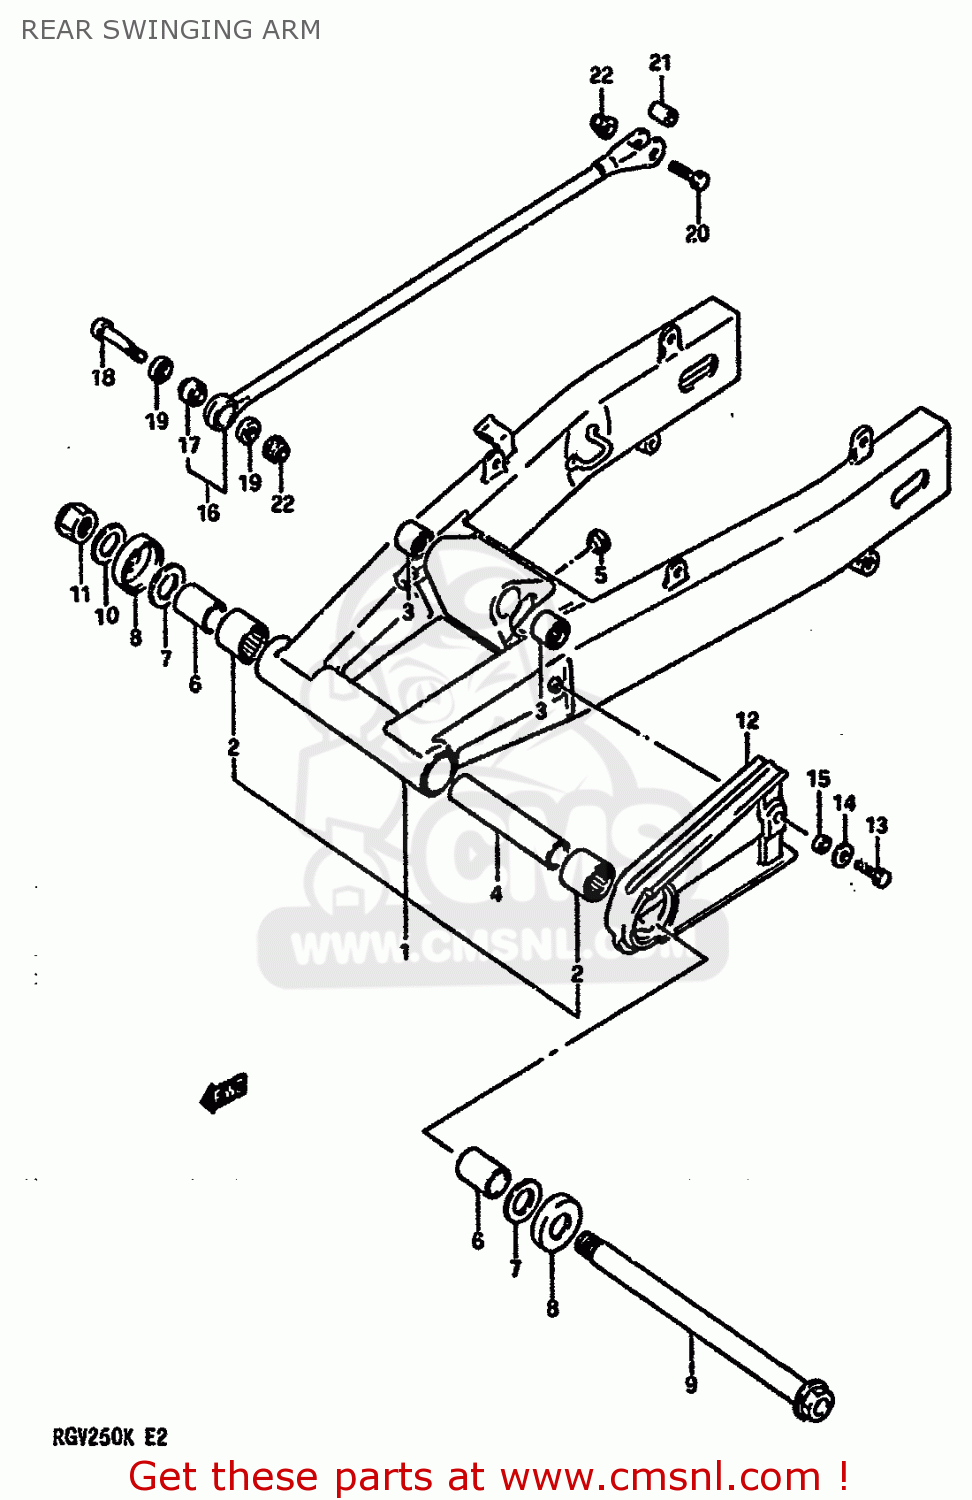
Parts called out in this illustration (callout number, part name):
1	SWINGING ARM ASSY,REAR
2	BEARING(25X33X30)
3	BEARING(17X24X20)
4	SPACER,RR SWGARM PIVOT CTR
5	PLUG(OD:17)
6	SPACER,RR SWGARM PIVOT BERRING
7	WASHER
8	DUST SEAL,RR SWGARM PIVOT
9	SHAFT,RR SWINGINGARM PIVOT
10	WASHER
11	NUT
12	BUFFER,CHAIN TOUCH DEFENSE
13	BOLT
14	WASHER (6.5X18X1.6)
15	SPACER
16	TORQUE LINK SET,REAR
17	SPHERICAL BEARING,TORQUE
18	BOLT(8X48)
19	20
20	BOLT
21	SPACER,RR TORQUE LINK RR
22	NUT
